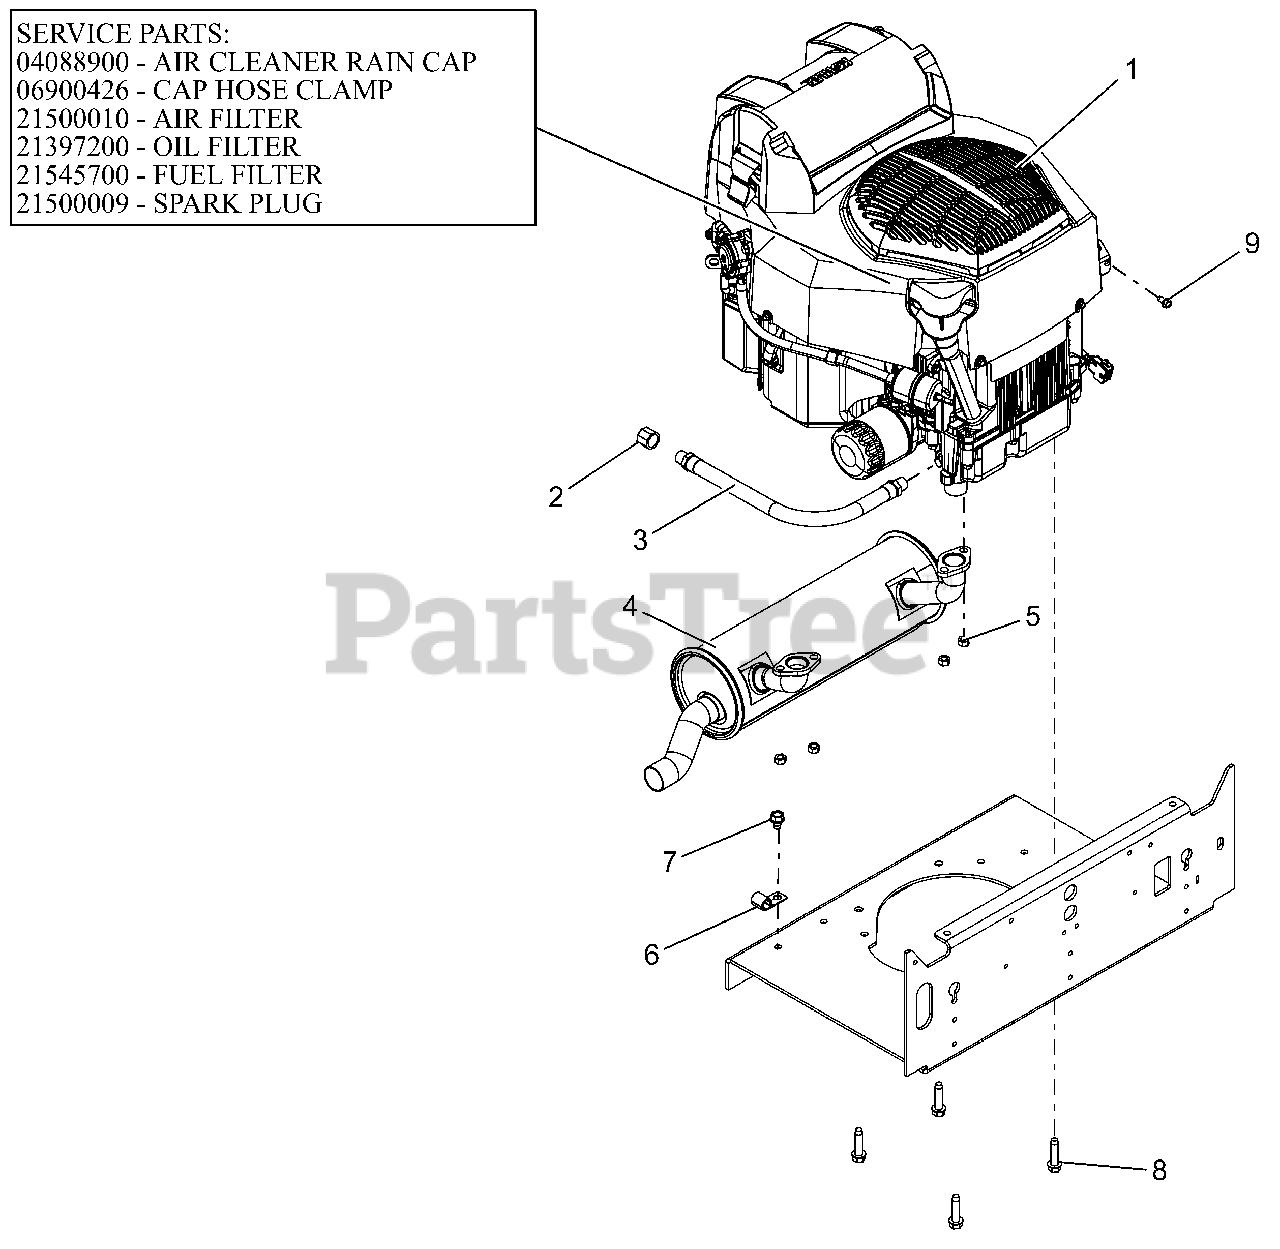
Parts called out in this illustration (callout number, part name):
1	ENGINE, KOHLER ZT740 CONFIDANT
1	CAP, KAW 11065-7025
1	CLAMP, HOSE #36 SS 1.813-2.75
1	AIR CLEANER, KOHLER CONFIDANT
1	FILTER, OIL - KOH CV20
1	FILTER-FUEL KOHLER COURAGE PRO
1	PLUG, SPARK KOHLER
2	PIPE CAP 3/8 NPT FEMALE
3	HOSE,HYD .38-14-0K M6N0-M6N0
4	MUFFLER, ZT730/ZT740
5	NUT-LK-TOP M8-1.25 YWZC
7	@SCR-TAP .38-16X.50 HWH TR YWZ
8	@SCR-TAP .38-16X1.50 HWH TR YZ
9	SCR-TAP .25-20X.50 HWH TR YWZ
